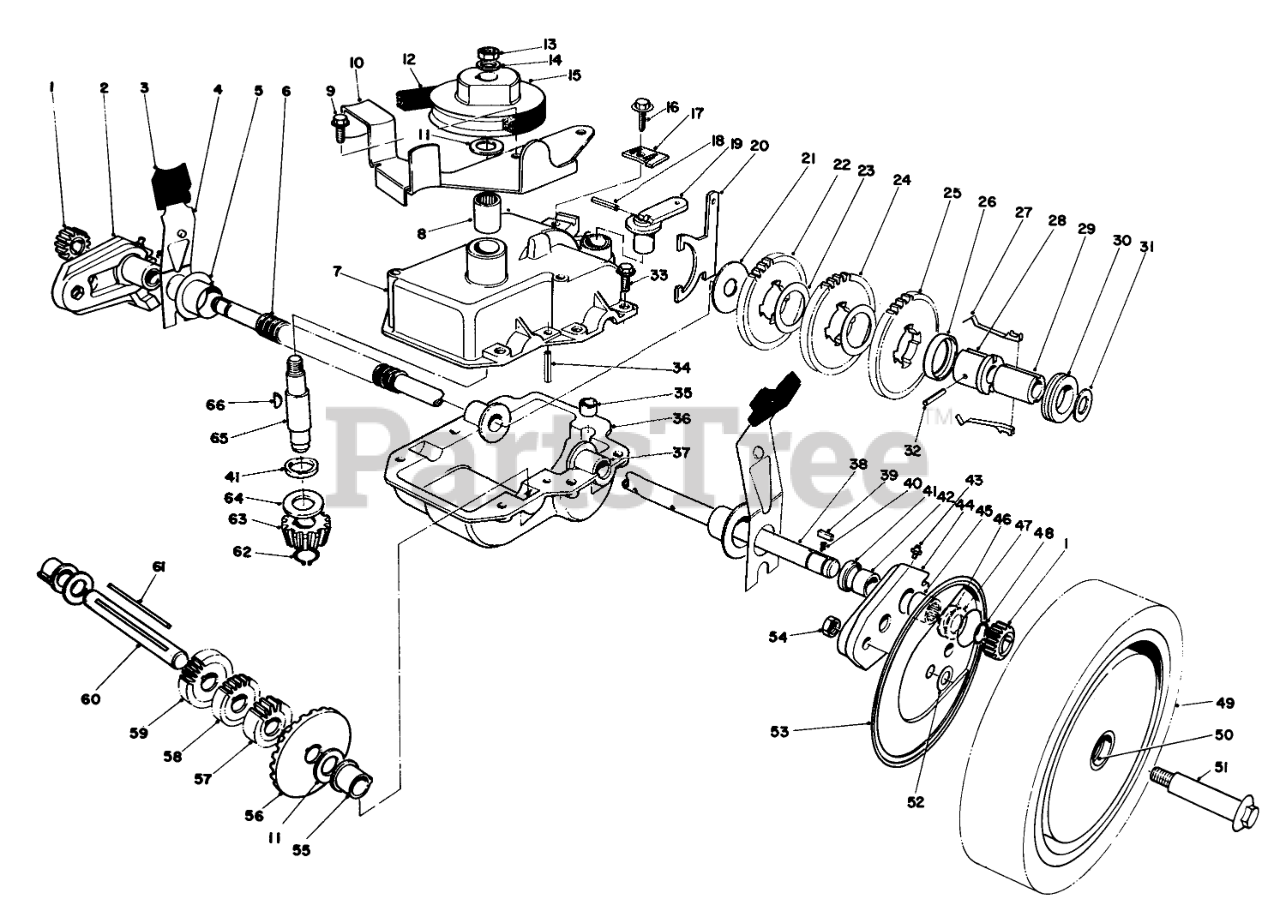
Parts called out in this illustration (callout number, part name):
1	GEAR-PINION
2	Pivot Arm Assembly-R.H. (Incl. Ref. #41-43 & 45)
3	KNOB-ARM
4	SPRING ARM ASM SP
5	CAP-END
6	CONDUIT-CONVOLUTED, SPLIT
7	Case-Upper
8	BEARING
9	SCREW
10	BELT GUIDE BRKTB
11	WASHER-THRUST
12	V-BELT
13	NUT-LOCK
14	WASHER-FLAT
15	PULLEY
16	SCREW-HWHTF
17	Cable Clamp
18	PIN-COIL
19	LEVER-SHIFT
20	Shift Yoke
21	WASHER
22	GEAR-38T
23	WASHER
24	GEAR-42T
26	KEY RETAINER
27	KEY-SHIFT
28	Body-Sleeve
29	SLEEVE
30	COLLAR-SHIFT
31	WASHER-PLAIN
32	PIN-SPRING
33	SCREW-HWHTF
34	ROLL PIN 3/16 X 1 IN
35	BUSHING-YOKE
36	LOWER GEAR CASE CAST
37	Bushing-Output Shaft
38	Output Shaft
39	KEY RECTANGULAR
40	SPRING-COMPRESSION
42	BUSHING
43	FITTING-GREASE
44	Pivot Arm Assembly-L.H.(Incl. Ref. #41-43 & 45)
45	BEARING-ROLLER
46	INNER THRUST WASHER
47	WASHER-THRUST, OUTER
48	RING-RETAINING
49	Wheel, Tire & Gear Assembly (Incl. Ref. #50)
50	BUSHING
51	WHEEL BOLT
52	WASHER
53	WHEEL COVER
54	NUT-LOCK
55	BUSHING
56	BEVEL GEAR
57	GEAR-12T
58	GEAR-14T
59	GEAR-18T
60	INTERMEDIATE SHAFT
61	Key Square
62	RING-RETAINING
63	PINION-BEVEL
64	WASHER-THRUST
65	INPUT SHAFT
66	KEY-WOODRUFF
